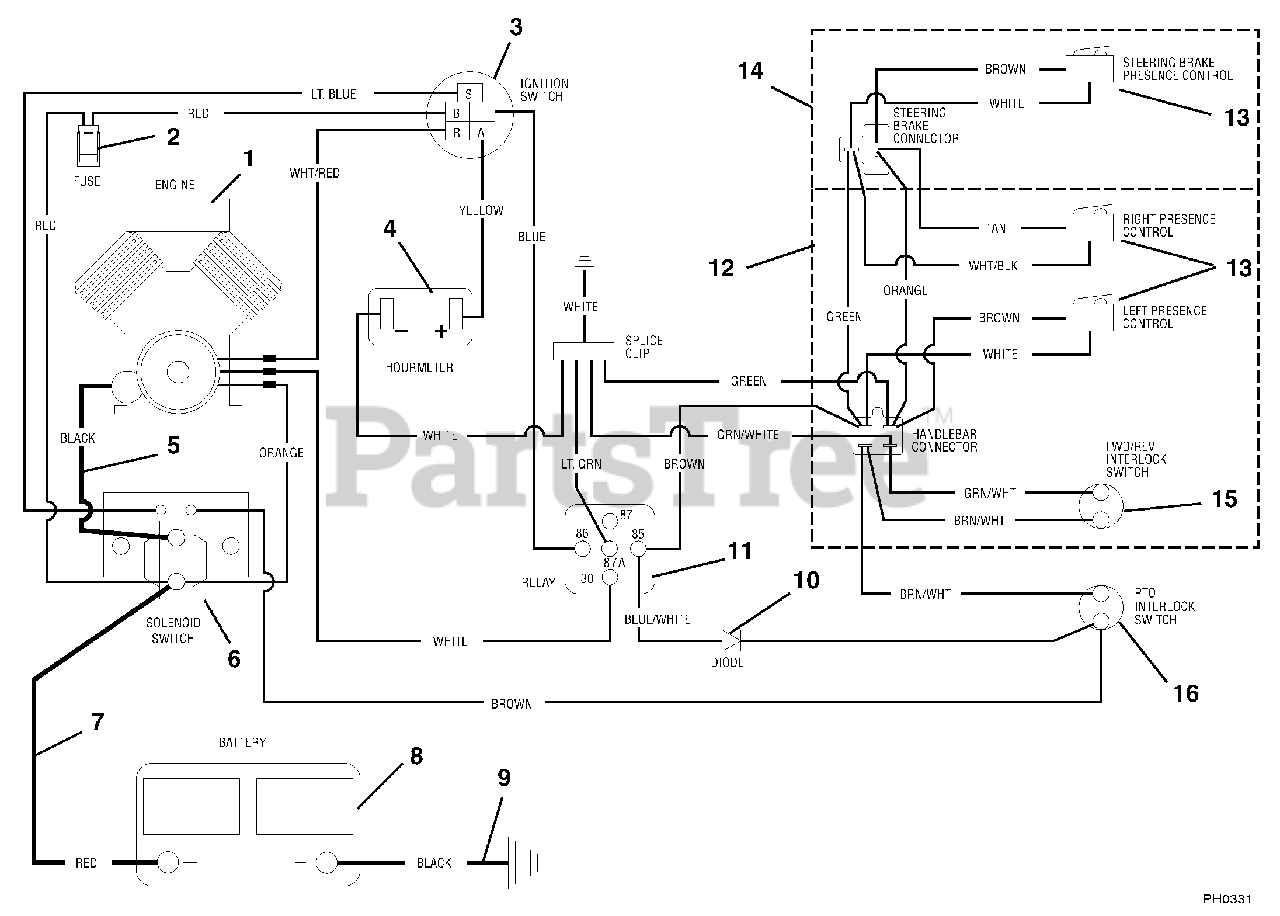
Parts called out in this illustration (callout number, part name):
1	Engine, Briggs and Stratton 16HP V Twin H/S
2	Fuse, 25 AMP
3	Ignition Switch
4	Hour Meter
5	Cable
6	Solenoid
7	Cable, Battery-To-Solenoid
9	Cable, Negative Battery 35"
10	Molded Diode Plug- Clear 1 AMP
11	Relay
12	Harness, Wiring Handlebar
13	Switch
14	Harness, Steering Brake
15	Switch,Interlock Closed (Forward/Reverse)
16	Switch,Interlock Open (PTO)
